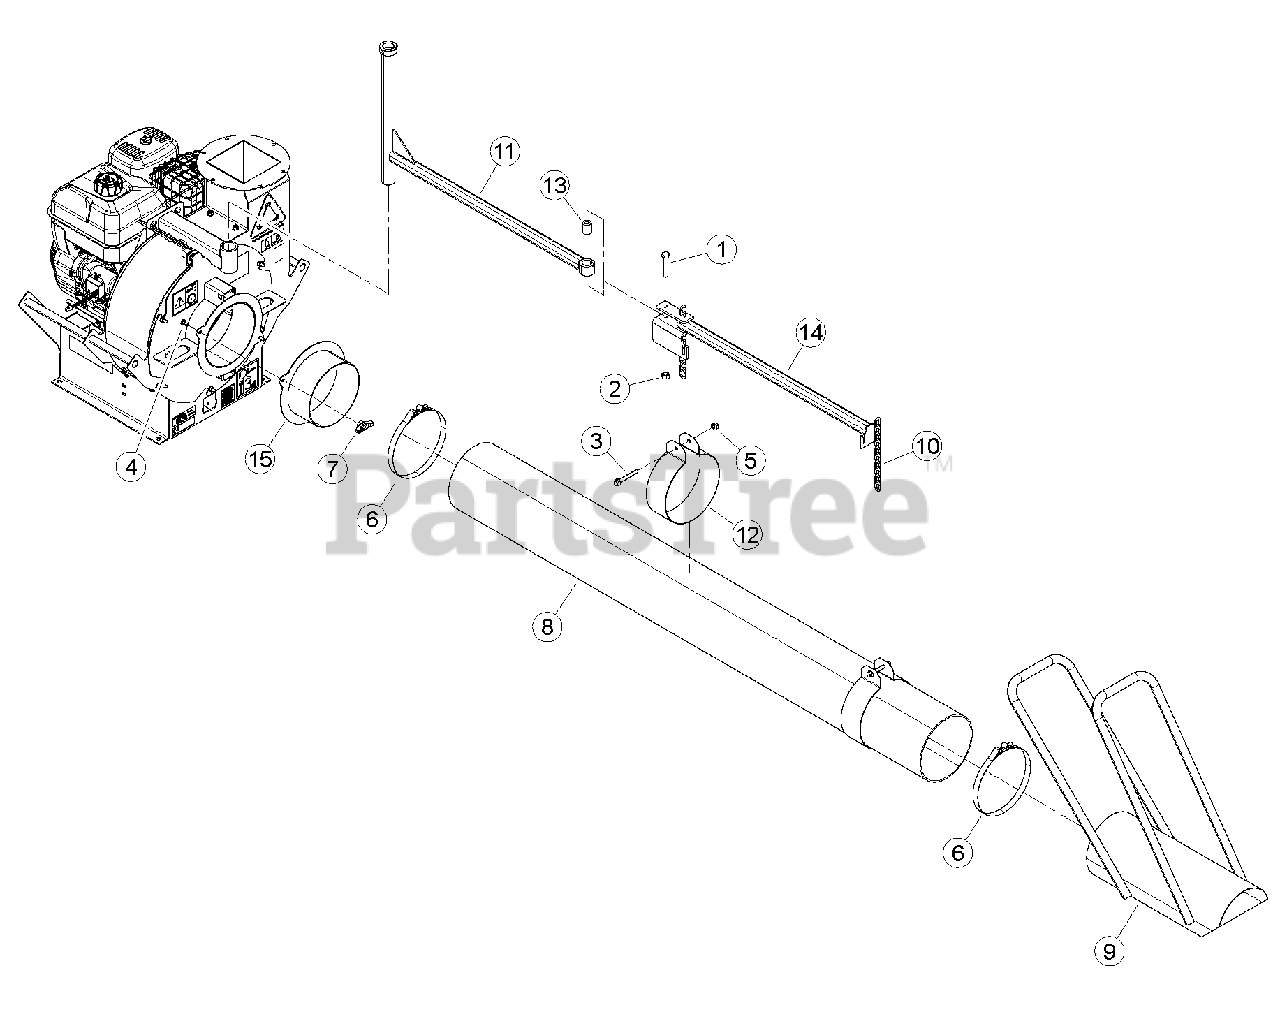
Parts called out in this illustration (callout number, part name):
1	BOLT, 1/2 X 2-3/4 HEX GR5 ZP
2	NUT, 1/2-13 GR5 CENTERLOCK GRB
3	BOLT, 3/8 X 3 FLANGE NC
4	BOLT, 5/16 X 3/4 GR5 CRG NC ZP
5	NUT, 3/8-16 NYLOCK FLANGE
6	CLAMP, T-BOLT 8-3/8"
7	KNOB, 5/16-18 UNC TEE W/ LOCKING INSERT
8	HOSE, 8 INCH X 12-1/2 FT
9	WELDMENT, HOSE INLET
10	CHAIN, HOSE SUPPORT
11	WELDMENT, HOSE SUPPORT
12	WRAP, HOSE SUPPORT
13	SPACER, 1.00 OD X 0.25 X 1.26
14	WELDMENT, HOSE SUPPORT
15	WELDMENT, INLET ADAPTER
